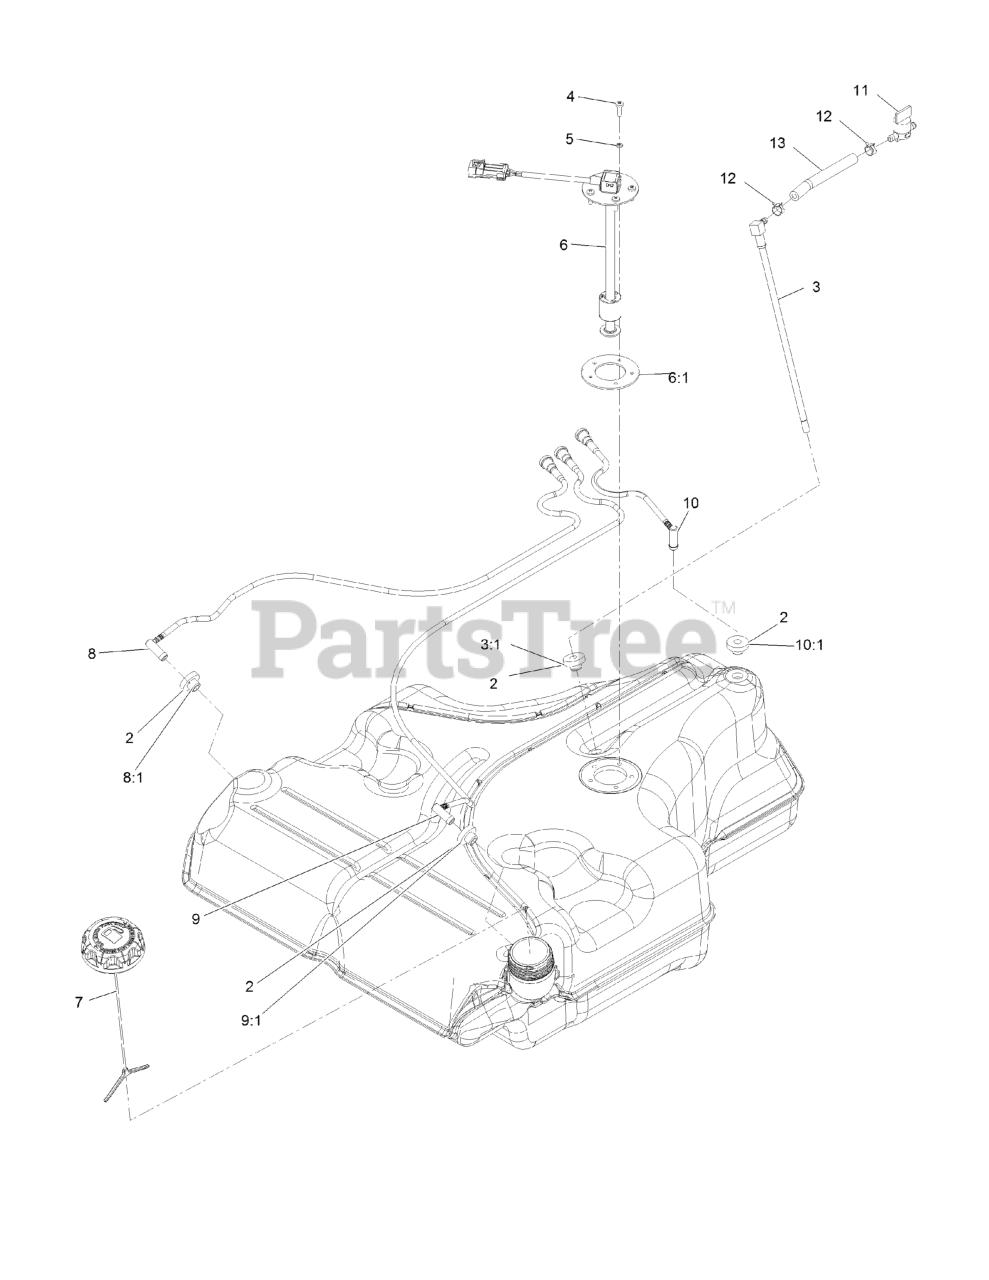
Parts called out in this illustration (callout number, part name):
2	BUSHING
3	FUEL LINE KIT (WITH GROMMET)
3:1	BUSHING
4	SCREW-PPH
5	WASHER-LOCK
6	FLOAT-SENDER, FUEL
6:1	Gasket-Sender
7	CAP-FUEL, RATCHETING
8	RH VENT LINE KIT (WITH GROMMET)
8:1	BUSHING
9	LH VENT LINE KIT (WITH GROMMET)
9:1	BUSHING
10	REAR VENT LINE KIT (WITH GROMMET)
10:1	BUSHING
11	VALVE-FUEL
12	CLAMP-HOSE
13	HOSE-FUEL
